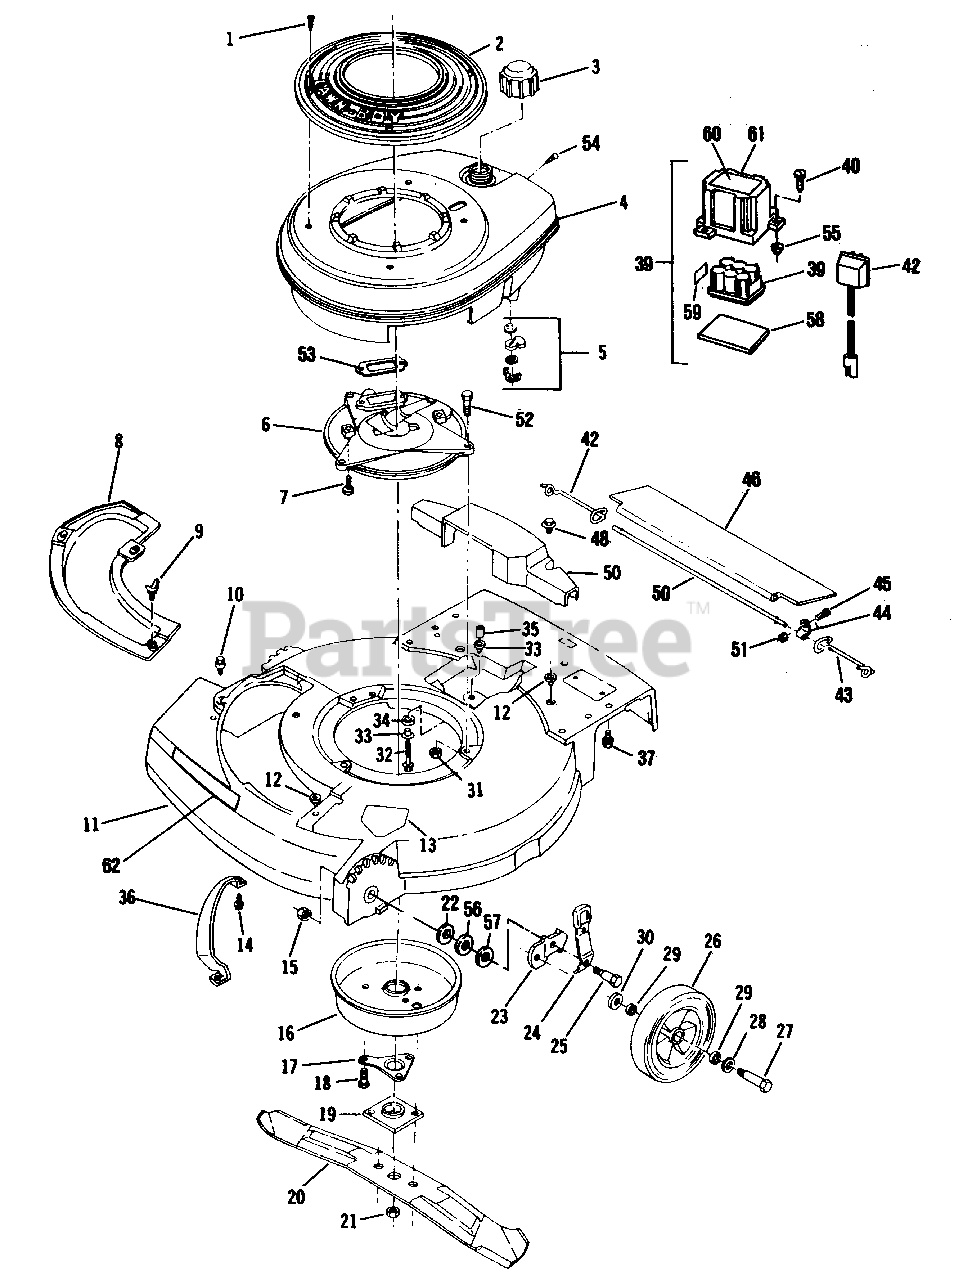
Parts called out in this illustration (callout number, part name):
1	Screw
2	Cover-Shroud
4	Shroud-Engine
5	Fuel Shut-Off Assembly
6	Plate-Muffler
7	Screw-Muff. Plt. to Blk.
8	Cover Plate
9	Wing Screw
10	Screw Plt. and Chute Mtg.
11	Housing
12	Grommet
13	Decal-Blade Contact Warning
14	Screw
15	Nut
16	Muffler Cover Assembly
17	Support-Crankshaft
18	Screw-Muff. to Muff. Plt.
19	Collar and Plate Assembly
20	Blade-21"
21	Nut-Blade
22	Washer
23	Bracket-Whl. Hgt. Adj.
24	Knob and Spring Assembly
25	Bolt-Shoulder
26	Wheel-Front
27	Bolt-Wheel-Front
28	Washer
29	Washer-Felt
30	Washer
31	Nut-Muff. Plt. to Housing
32	Screw
33	Spacer
34	Grommet
35	Spacer
36	Toe Bar
37	Screw-Handle Bracket
39	Batt. Pack Ass'y.
40	Screw-Batt. Cover
42	Battery Charger Assembly
43	Spring-L.H.
44	Clamp
45	Screw
46	Shield-Trailing
47	Spring-R.H.
48	Screw-Axle Cover Mounting
49	Cover-Drive Axle
50	Rod-Trailing Shield
51	Nut
52	Screw-Muff. Plt. to Hsg.
53	Gasket-Exhaust
54	Screw-Shroud to C.D. Brk't.
55	Grommet-Batt. Mtg.
56	Washer-Shim
57	Washer-Shim
58	Pad Batt.
59	Decal-Batt.
60	Decal-Batt.
61	Cover-Batt.
62	Decal-Headliner
